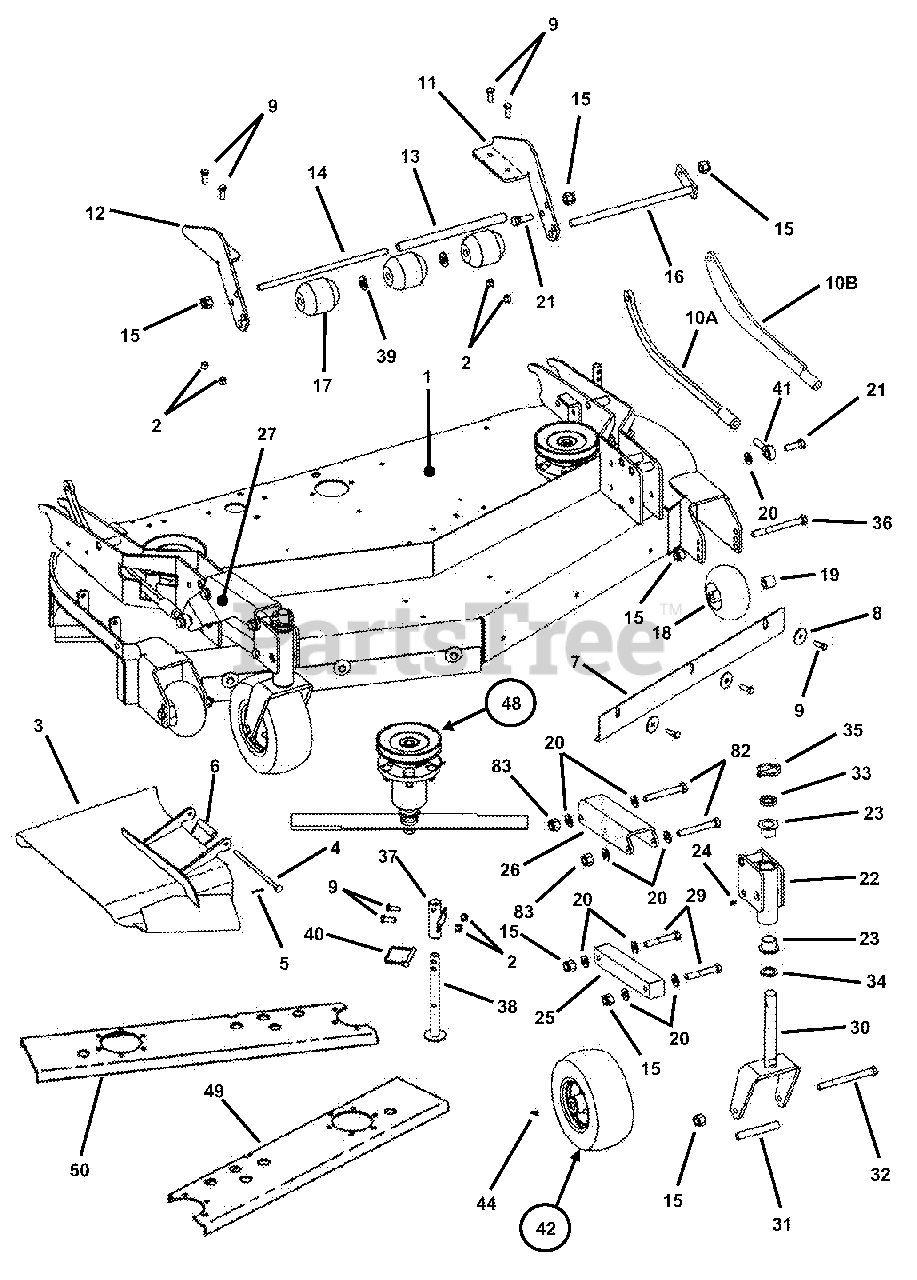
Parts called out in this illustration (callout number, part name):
1	WELDMENT, 61" Deck- Adjustable Height
2	NUT, 3/8-16 HEX NYLON LOCK
3	DEFLECTOR, Chute 61"
4	PIN, Chute Hinge
5	PIN, 3/32 x 1" Cotter
6	SPRING, Chute
7	BAFFLE, Front
8	WASHER, 13/32 x 1-1/2" Flat
9	BOLT, 3/8-16 X 1" GD5 CZ
10A	LINK, Height of Cut
10B	LINK, Height of Cut, Heavy Duty
11	MOUNT, Roller Left Hand
12	MOUNT, Roller Right Hand
13	TUBE, Roller
14	PIN, Roller
15	NUT, 1/2-13 Hex Nyloc
16	WELDMENT, Shaft
17	ROLLER, Low Density Polyethylene
18	WHEEL, Gage
19	SPACER, Gage Wheel
20	WASHER, 1/2" Flat
21	BOLT, 1/2-13 X 1-1/2 GD5 CZ
22	TUBE, Caster (Weldment)
23	BUSHING, Caster
24	FITTING, Lube 1/4-28 Straight
25	ARM, Lower Caster
26	ARM, Caster Support Left Hand
27	ARM, Caster Support Right Hand
28	BOLT, 1/2-13 x 3-3/4" Hex Head Cap, Grade 5
29	BOLT, 1/2-13 X 3" GD5 CZ
30	WELDMENT, Caster
31	SLEEVE, Axle
32	BOLT, 1/2-13 X 5-1/2" GD5 YZ
33	SPACER, 1" x 1 3/8 x .30" (PM)
34	BUSHING, Machine
35	PIN, 7/16" HD Lynch
36	BOLT, 1/2-13 X 5 GD5 YZ
37	TUBE, Jack Stand (Weldment)
38	WELDMENT, Jack Stand
39	WASHER, 5/8" Flat
40	PIN, 5/16" Lynch
41	BALLJOINT, 1/2-20
42	ASSEMBLY, Wheel/Tire
44	FITTING, Grease 1/4"
48	GROUP, Spindle
49	STIFFENER, 61" Deck, Left Hand
50	STIFFENER, 61" Deck, Right Hand
82	SCREW, 1/2-20 x 4-1/2" Hex Head Cap, Grade 5
83	NUT, 1/2-20 Hex
